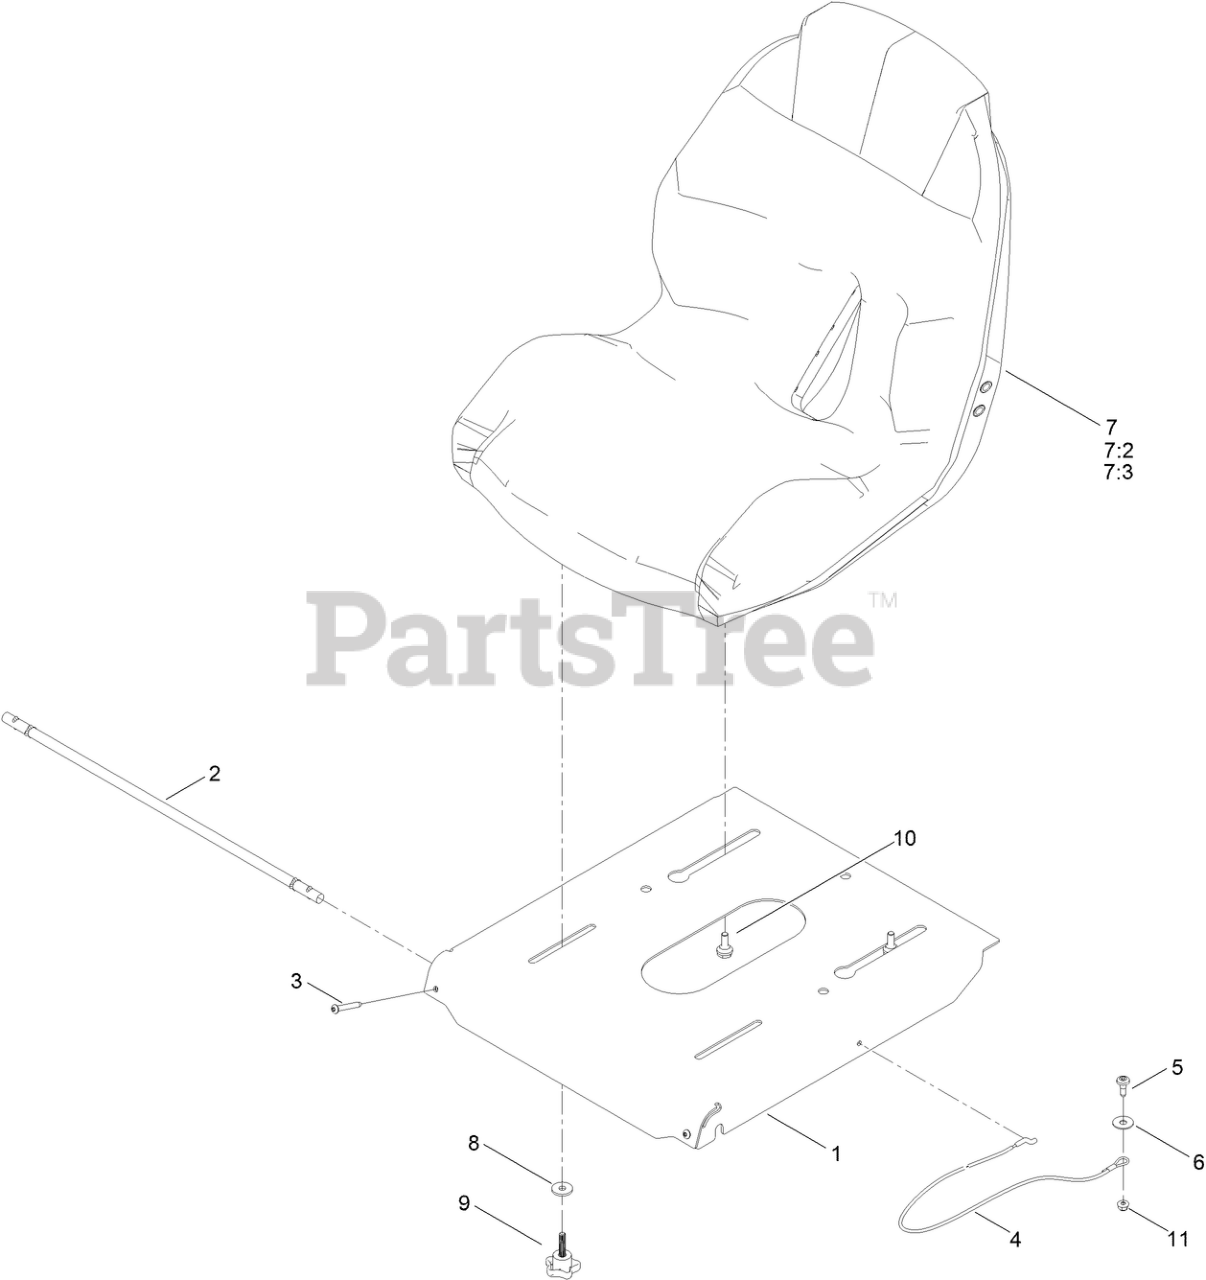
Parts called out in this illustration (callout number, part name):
1	PAN-SEAT
2	ROD-PIVOT
3	SCREW-TBH,THD ROLL
4	CABLE-LANYARD, 26.75"
5	SCREW-SHOULDER
6	WASHER-FLAT
7	SEAT ASM - SEAT KING SK130
7:2	COVER-SEAT
7:3	SWITCH-BAIL
8	WASHER-FRICTION
10	BOLT-SHOULDER,HFH
11	NUT-FLANGE, NI
